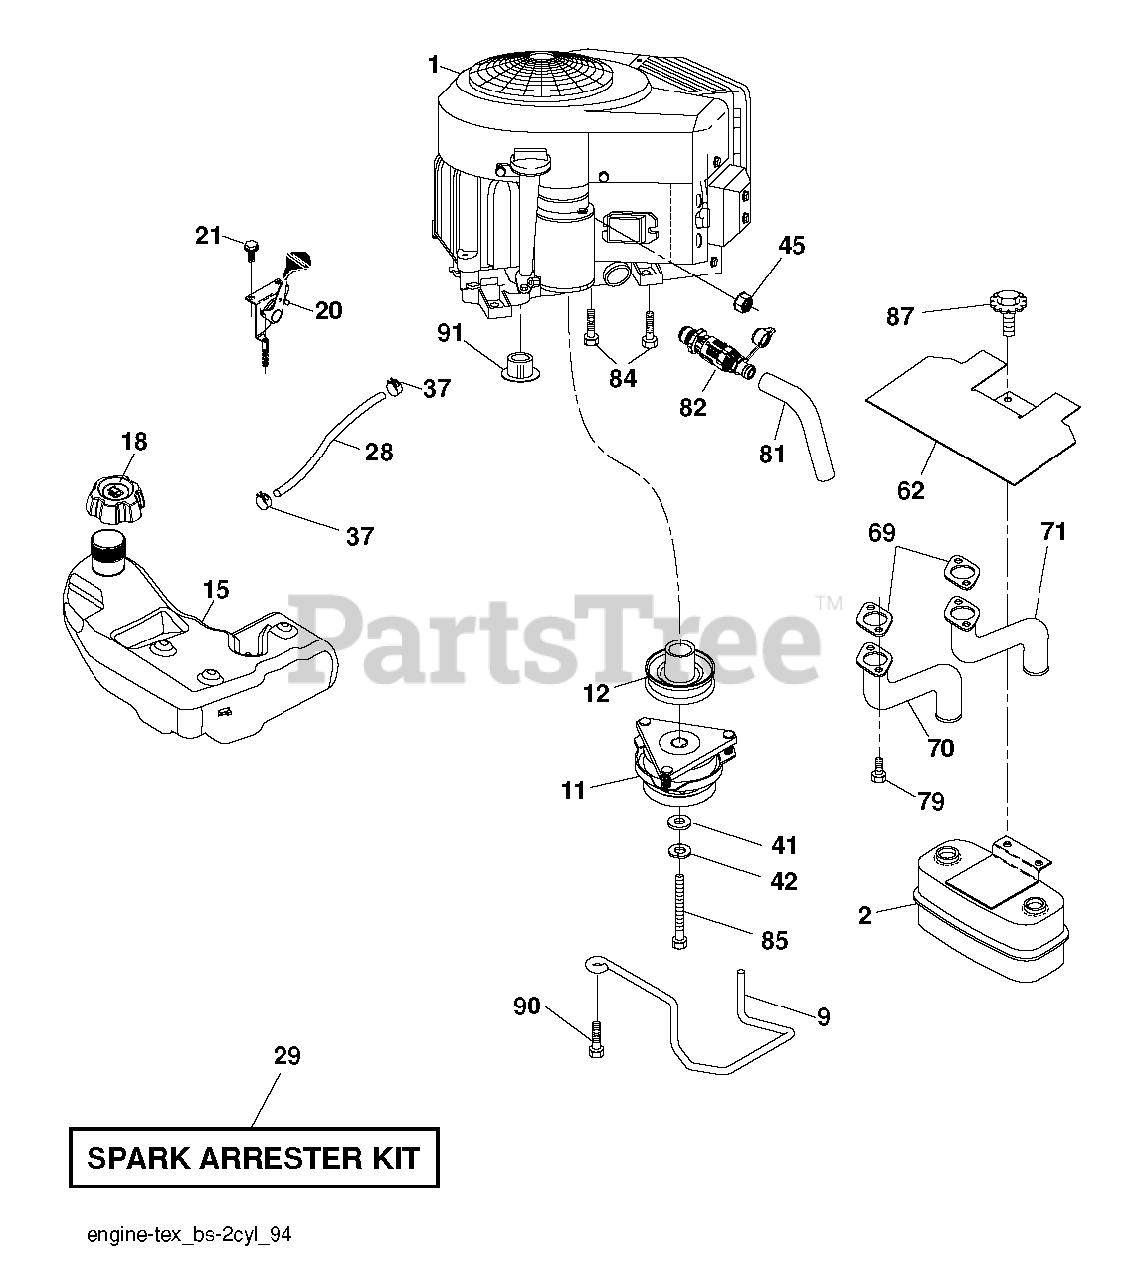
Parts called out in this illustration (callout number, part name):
2	MUFFLER.ASM.TWN.EXTNDED.DFLCTR
9	KEEPER BELT ENGINE
11	CLUTCH.ELECTRIC.LT.48"*
12	PULLEY.ENGINE.TUFFTORQ
15	TANK.ASSY.3.GAL.EPA
18	CAP.ASM.FL.RITCH.3"E10.SYM.498
20	CONTROL.TH/CK.COBRA.B&S.TWN.
21	SCREW.#10 X 0.750.BOS
28	LINE.FUEL.64"REAR.EMIS
29	KIT.SPARK ARRESTOR 794945 B&S
37	HOSE CLAMP
42	LOCKWASHER
45	NUT
62	SHIELD.HEAT.MUFFLER
69	SPRING.BYPASS.CRD
70	EXHAUST.TUBE.LH.BS/TWIN
71	EXHAUST.TUBE.RH.B&S.TWIN.INTEK
79	SCREW.SOCKET.HEAD.5/16-18
81	TUBE, DRAIN OIL ASM.
82	VALUE.OIL.DRAIN
84	SCREW.3/8-16
85	BOLT HEX 7/16-20X4-1/4"
87	BOLT, 5/16-18 X 1 3/4
90	SCREW 3/8-16X1
91	BUSHING.1.375OD
